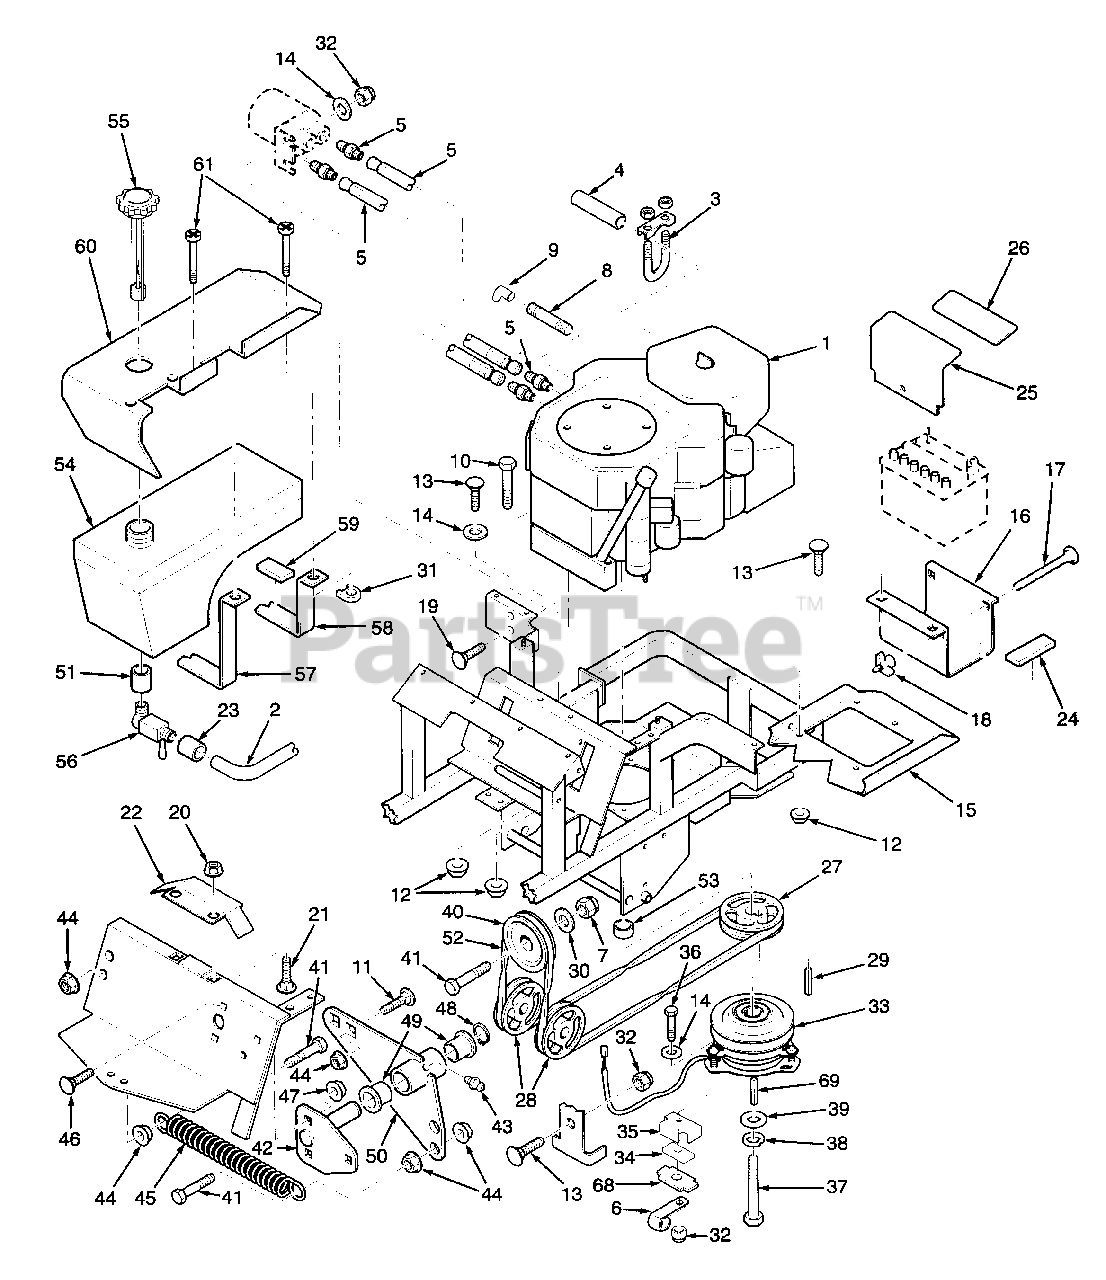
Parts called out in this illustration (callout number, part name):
1	Engine 18 hp Kohler CV For SSZ-18CV
2	Fuel Hose
3	Muffler Clamp
4	Tube, Exhaust
5	Kohler Fittings
6	Clamp, 50 ID
7	Nut, 3/8-16 Elastic Stop
8	Extention, 2.50"
9	Elbow, Street
10	Bolt, 5/16-18 x 1-1/2" Serr. Flng. Hex Head
11	Bolt, 7/8-16 x 1.50" Carriage
12	Nut, Serrated Flange Hex Head 5/16-18
13	Bolt, Carriage 5/16-18 x 3/4"
14	Flatwasher, 5/16" (.313 x .875 x .083)
15	Fender, LH
16	Battery Box
17	Bolt, Carriage 1/4-20 x 6"
18	Wing Nut, 1/4-20
19	Bolt, Carriage 5/16-18 x 1"
20	Nut, Serrated Flange Hex 1/4-20
21	Bolt, Carriage 1/4-20 x 3/4"
22	Belt Guard
23	Fuel Hose Clamp
24	Rubber Pad
25	Battery Cover
26	Pad, Battery Cover
27	Pulley
28	Pulley, Pump
29	Key, 1/4 x 1/4 x 1-1/2"
30	Flatwasher, 3/8" (.391 x .938 x .105)
31	U-Nut, 1/4-20
32	Nut, Elastic Stop 5/16-18
33	Electric Clutch
34	Rubber Pad, Clutch Stop
35	Backing Plate
36	Bolt, Hex Head 5/16-18 x 1-3/4"
37	Bolt, Hex Head 7/16-20 x 3.00"
38	Lockwasher, 7/16"
39	Flatwasher, Retainer
40	Idler, Pulley
41	Bolt, Hex Head 3/8-16 x 1.75"
42	Pivot Weldment, Idler Arm
43	Grease Fitting
44	Nut, Serrated Flange Hex 3/8-16
45	Spring, Pump Drive Idler
46	Bolt, Carriage 5/16-18 x 3/4
47	Nut, Serrated Flange Hex 5/16-18
48	Ring, Retaining 1.125 Diameter External "E"
49	Bushing, 1.125 Sintered
50	Idler Arm Weldment, Pump Drive
51	Bushing, Fuel Tank Valve
52	Belt, Pump Drive
53	Spacer, Crankshaft
54	Fuel Tank
55	Fuel Tank Cap
56	Fuel Shut-off Valve
57	Fuel Tank Strap, Long
58	Fuel Tank Strap, Short
59	Rubber Pad
60	Fender Assembly, RH
61	Screw, Machine 1/4-20 x 2" Phillips Head
68	Backing Plate
69	Key, 1/4 x 1/4 x 2.75
